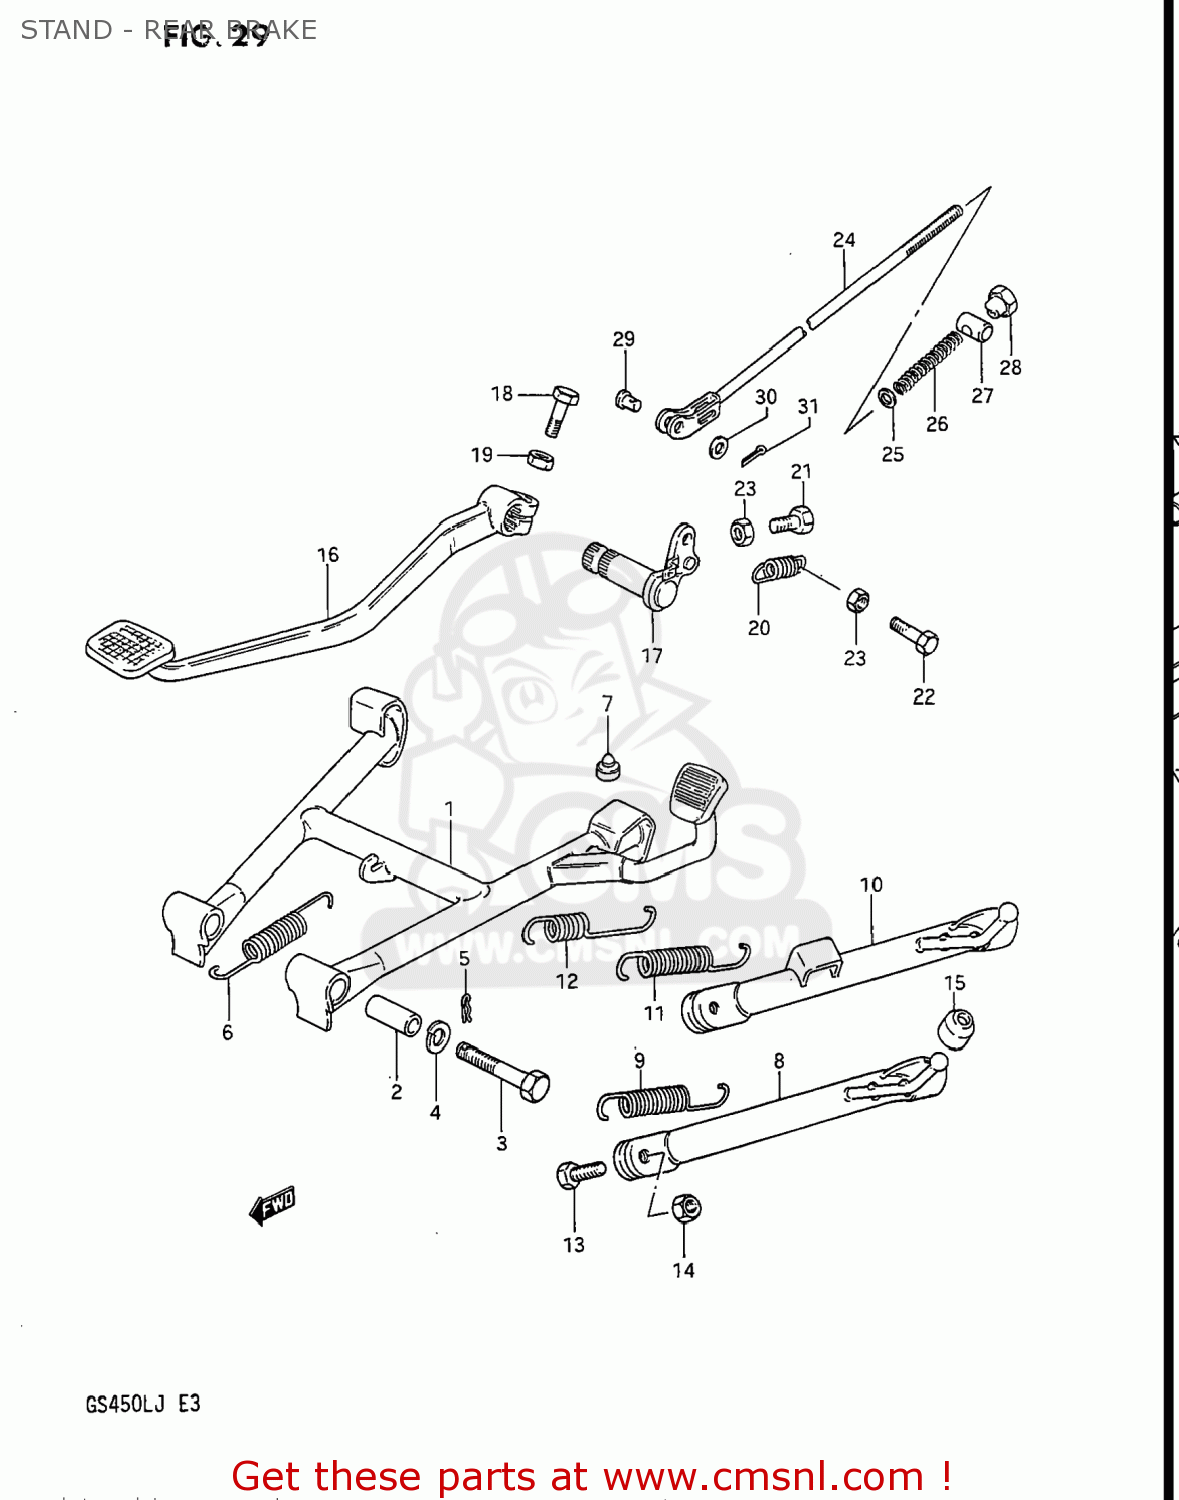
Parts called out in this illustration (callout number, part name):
1	STAND,CENTER
2	SPACER(10X16X38.8)
3	BOLT
4	WASHER,LOCK,10
5	CLIP
6	SPRING
7	CUSHION
8	STAND,SIDE
9	SPRING
10	STAND,PROP
11	SPRING
12	SPRING
13	BOLT L:30
14	NUTM10X1.25X8
15	CUSHION
16	PEDAL,BRAKE
17	ARM,BRAKE PEDAL
18	BOLT
19	LOCK WASHER
20	SPRING
21	BOLT
22	BOLT
23	NUT 6MM
24	ROD ASSY,RR BRAKE
25	WASHER
26	SPRING
27	PIN
28	NUT (6MM)
29	PIN(L:13.5)
30	WASHER
31	PIN 20X20
